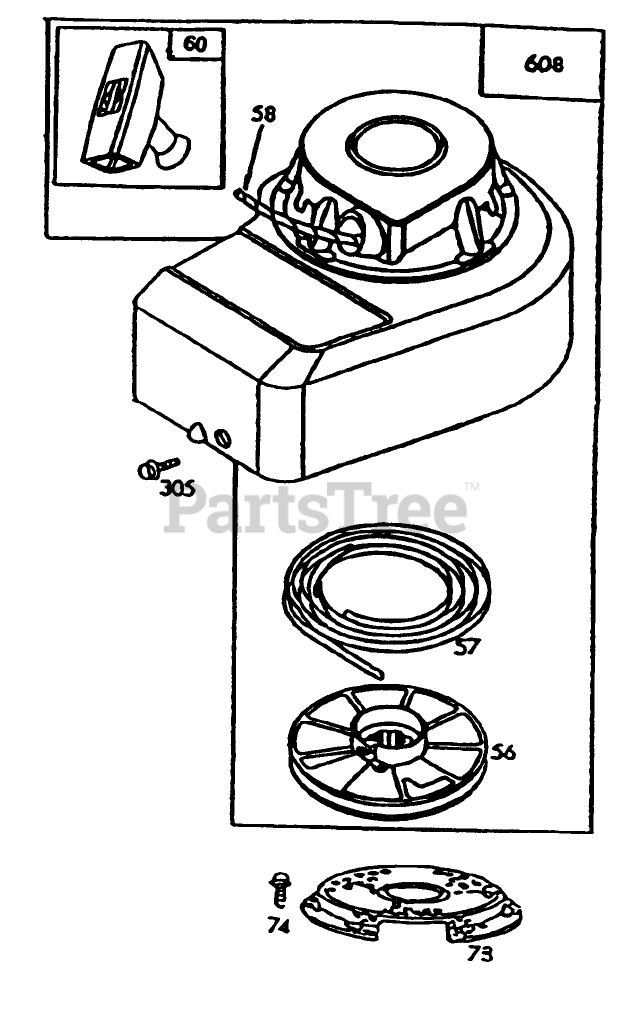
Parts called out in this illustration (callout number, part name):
56	Pully-Starter
57	Spring-Rewind
58	Insert-Starter Grip
60	Grip-Starter Rope
73	Screw-Sem
74	Screw-Sem
305	Screw-Blo. Hsg. Mtg.
608	Sorter Assy.-Rewind
